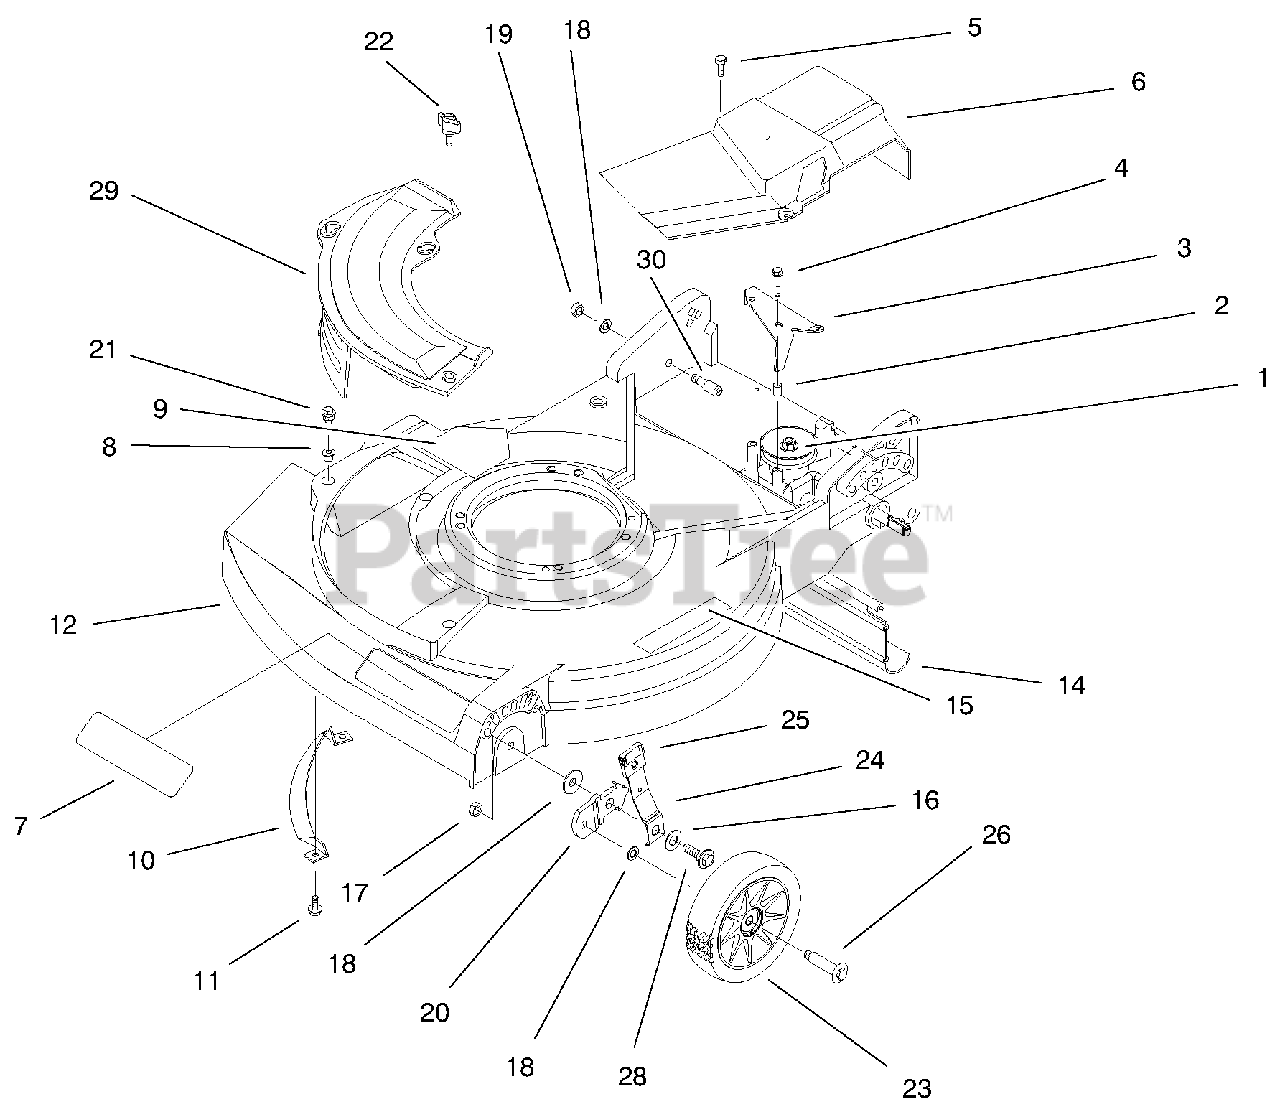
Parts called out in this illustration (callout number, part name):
1	ASM-Gear Case
2	Bushing-Spacer
3	Bracket-Actuator
4	Screw
5	Screw-Thread Forming
6	Cover-Drive
7	Decal-Deck
8	Grommet-Plastic
9	Decal-Danger
10	Toe Bar 21
11	Screw-HWH
14	Shield-Trailing
15	Decal-Warning
16	Washer-Spring
17	Nut-Lock
19	Nut-Lock
20	Bracket-Wheel Height Adj
21	Screw-Sems
22	Knob-Cover Plate
23	ASM-Wheel & Tire 6"
24	ASM-Spring Arm
25	Knob-Height Adjust
26	Bolt-Shoulder
28	Bolt-Shoulder
29	Mulch Plate-21"
30	Bolt-Shoulder
